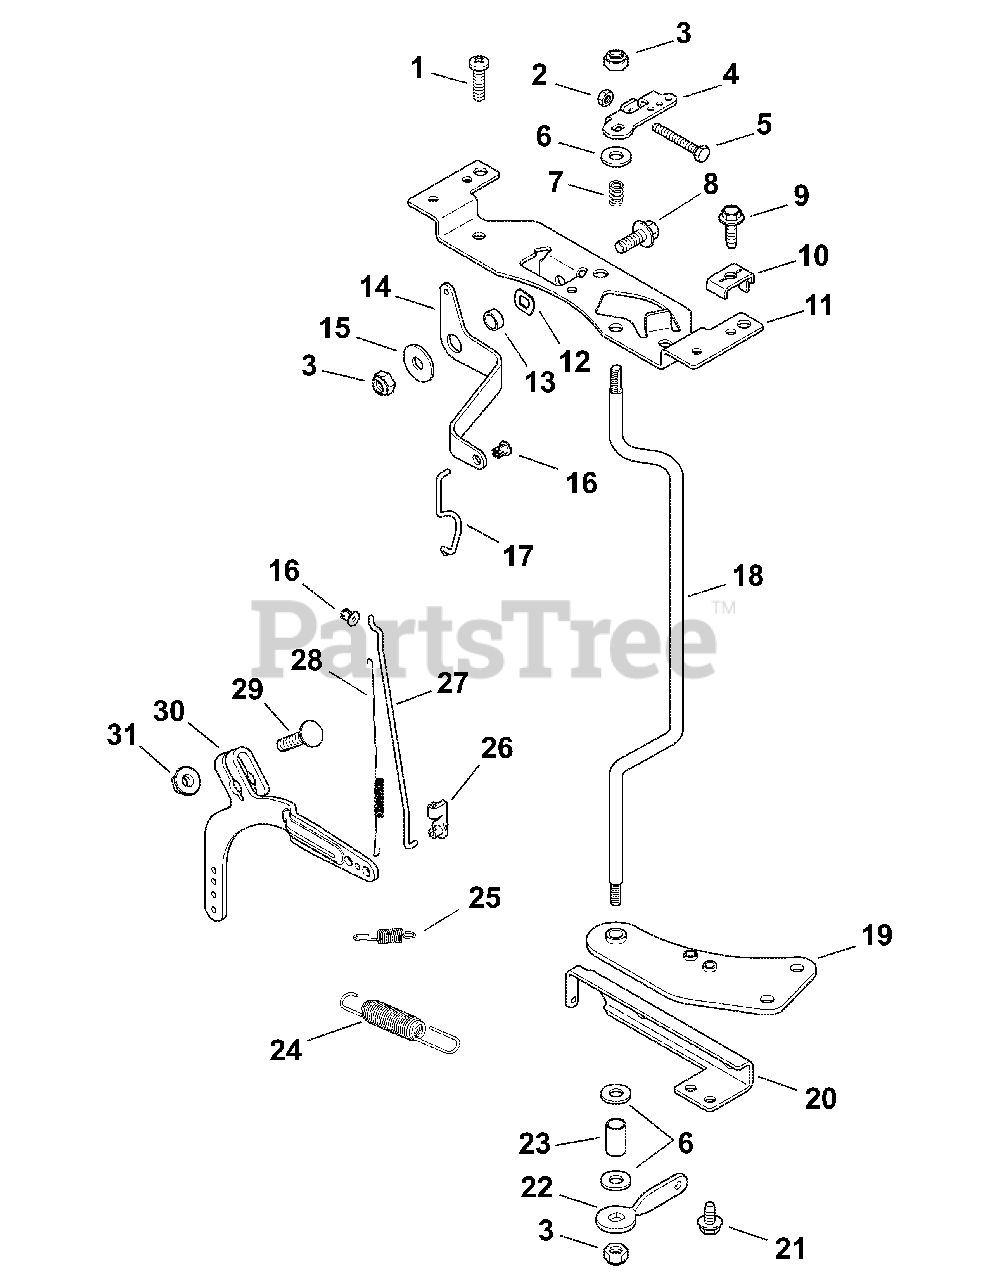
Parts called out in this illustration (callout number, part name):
1	Screw, Phl Hd 11-16X3/4"
3	Nut, Lock M6X1.0
4	Lever, Throttle Control
5	Screw, Cap M4X0.7X30
6	Washer, Flat 1/4"
7	Spring, Throttle Shaft
8	Screw, FLG M6X1.0X16
9	Screw, Flg Thd Frm M5X0.8X16
10	Clamp, Cable
11	Bracket, Control
12	Washer, Spring 3/8"
15	Washer, Flat 1/4"
16	Bushing, Linkage Retaining
17	Linkage, Choke
18	Shaft,Control
19	Bracket, Throttle Shaft
20	Bracket, Goverened Idle
21	Screw, Flg Thd Frm M5X0.8X10
22	Lever Throttle Control
24	Spring, Governor
25	Spring, Governor
26	Bushing, Throttle Linkage
27	Linkage, Throttle
28	SPring, Linkage
29	Bolt, Rd Hd Sq Neck M6X1.0X25
30	Lever, Governor
31	Nut, Flg M6x1.0
